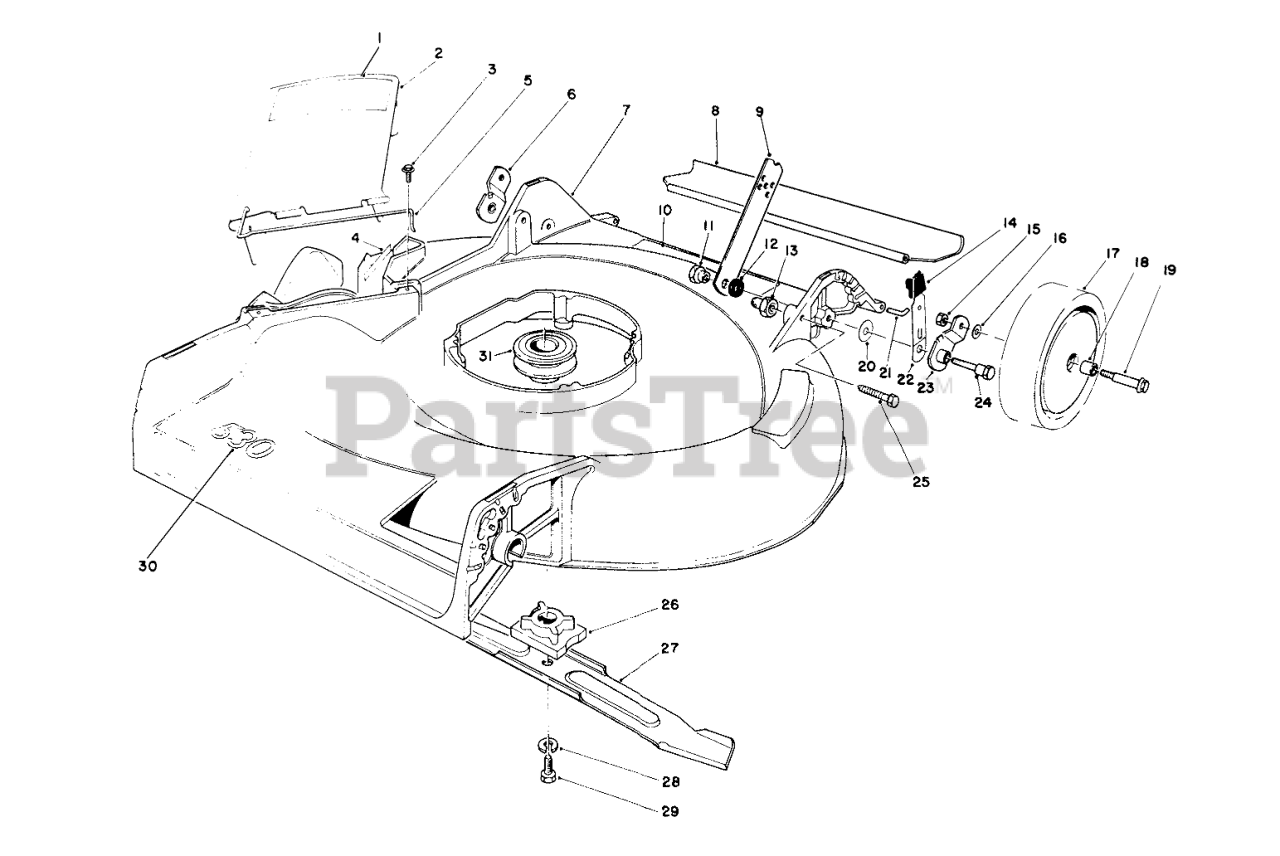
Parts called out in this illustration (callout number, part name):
1	DANGER DECAL
2	Deflector Assembly (Incl. Ref. #1 & 5)
3	SCREW-HWH
4	Decal-Danger
5	SPRING HINGE
6	Pivot Arm
7	Housing
8	REAR SAFETY SHIELD 21
9	HANDLE LATCH
10	DECAL-DANGER
11	HANDLE PIVOT NUT
12	SPACER
13	HANDLE PIVOT NUT
14	KNOB-ARM
15	NUT-LOCK
16	WASHER
17	Wheel 8 Tire Assembly (Incl. Ref. #18)
18	BUSHING
19	WHEEL BOLT
20	WASHER-PIVOT
21	SHIELD ROD
22	SPRING ARM ASM
23	Pivot Arm
24	PIVOT SCREW
25	SCREW-HH
26	BLADE RETAINER
27	Blade
28	WASHER-LOCK
29	SCREW-HH
30	Decal-530
31	PULLEY-DRIVER
